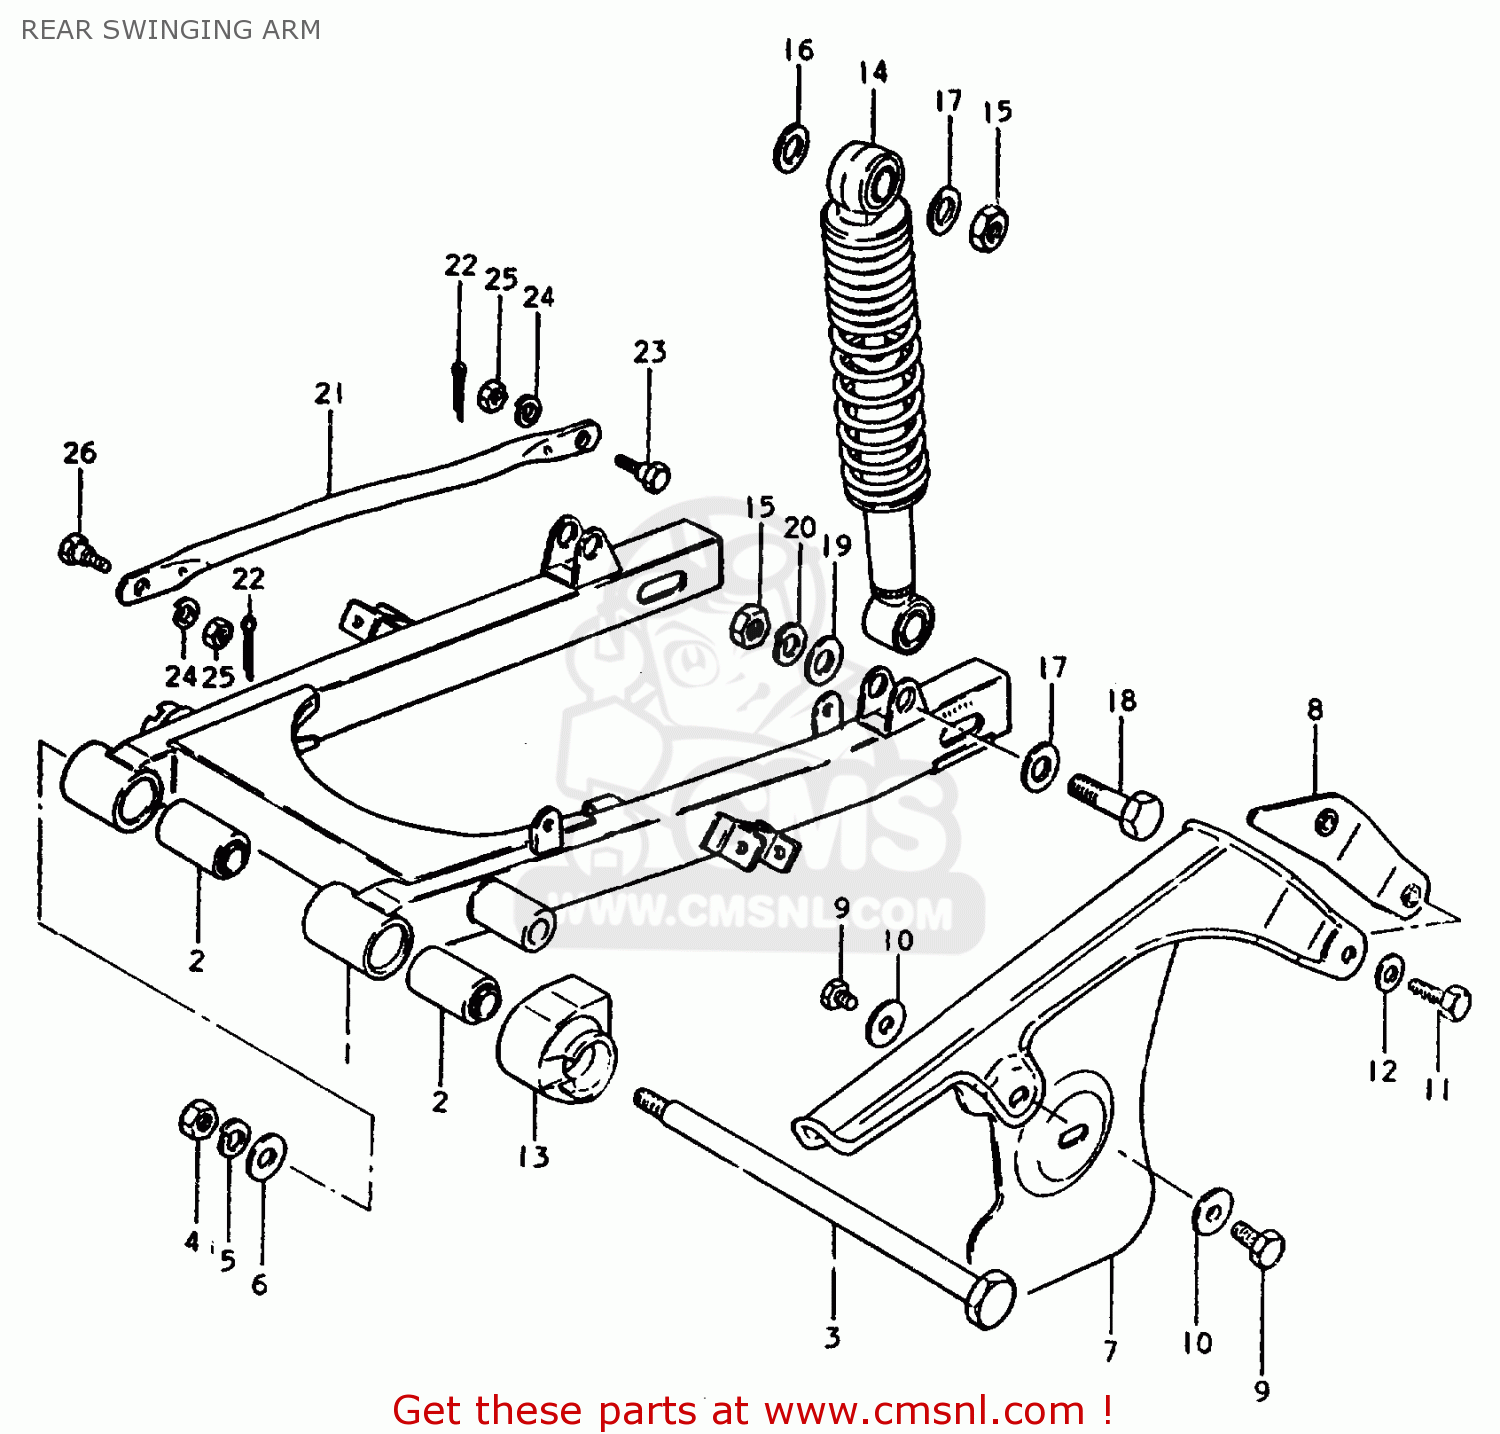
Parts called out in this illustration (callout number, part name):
1	SWINGING ARM, REAR (GOLD)
2	BUSH
3	SHAFT,REAR SWING ARM
4	NUT
5	LOCK WASHER
6	WASHER
7	CASE,CHAIN
8	REINFORCEMENT,CHAIN CASE
9	BOLT(6X8)
10	WASHER
11	BOLT, UPPER
12	WASHER
13	BUFFER
14	SHOCK ABSORBER, REAR
15	NUT
16	WASHER
17	WASHER
18	BOLT(10X36)
19	WASHER
20	LOCK WASHER
21	TORQUE LINK, REAR
22	PIN
23	BOLT(8X26.5)
24	LOCK WASHER
25	NUT
26	BOLT(8X22)
